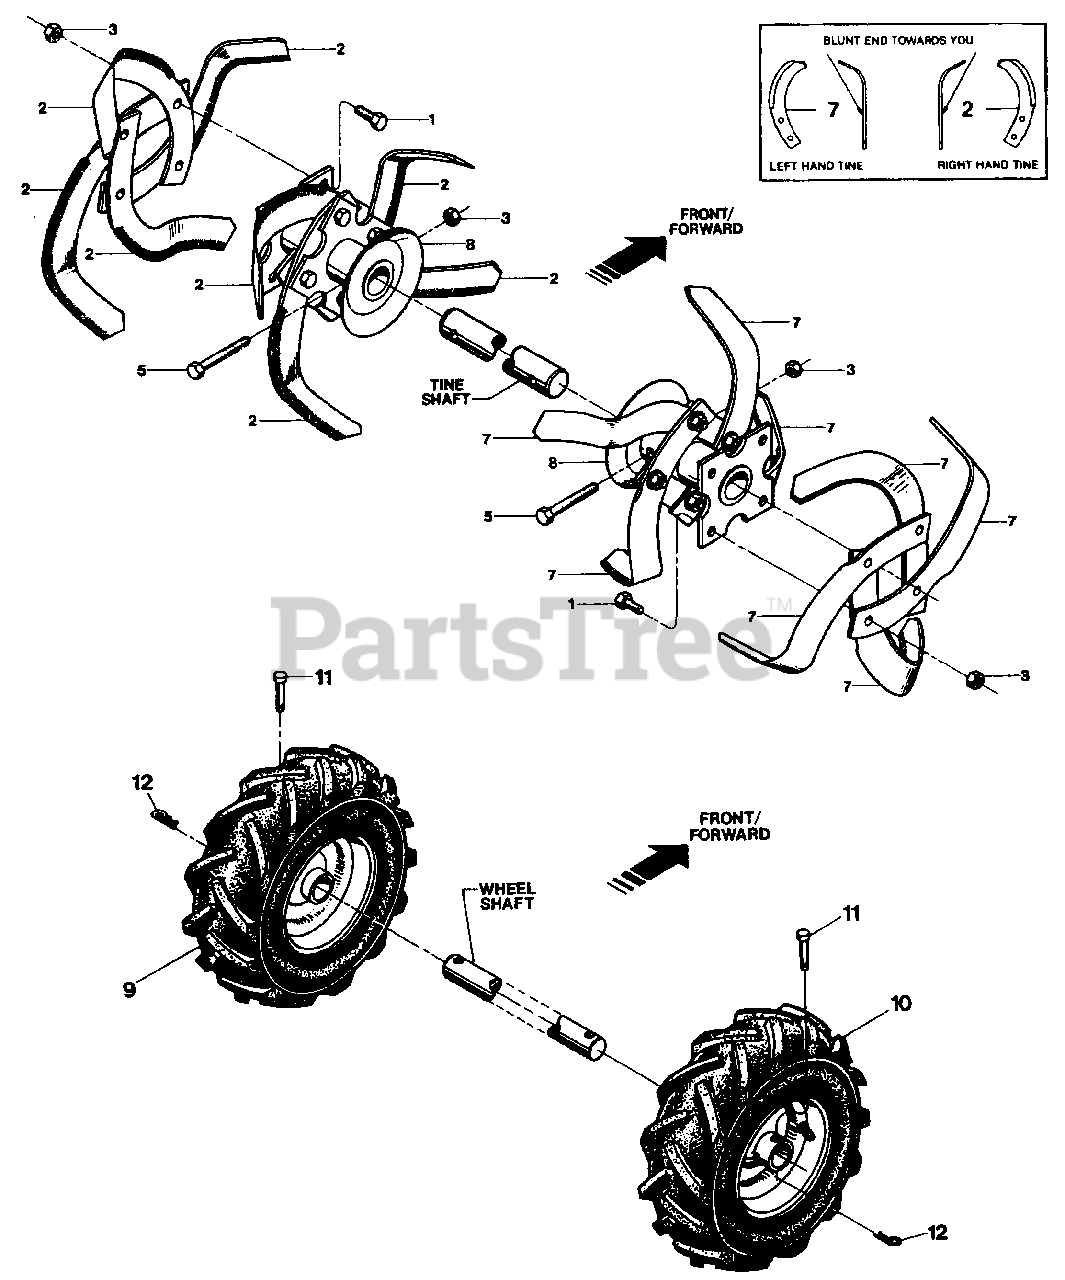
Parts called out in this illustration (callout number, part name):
1	Screw-hex hd., 3/8-16 x 1-1/4
2	Bolo Tine-single, right hand tine used on left side of tiller
3	Hex Locknut, 3/8-16
5	Screw-hex hd., 3/8-16 x 2, GRADE 8
7	Bolo Tine-single, left hand tine used on right side of tiller
8	Tine Holder-for bolo tines, left and right sides
9	Wheel & Tire Assy-left side, 4.10 x 6 tire
10	Wheel & Tire Assy-right side
11	Clevis Pin -.312 x 1-3/4 long
12	Hitch Pin
